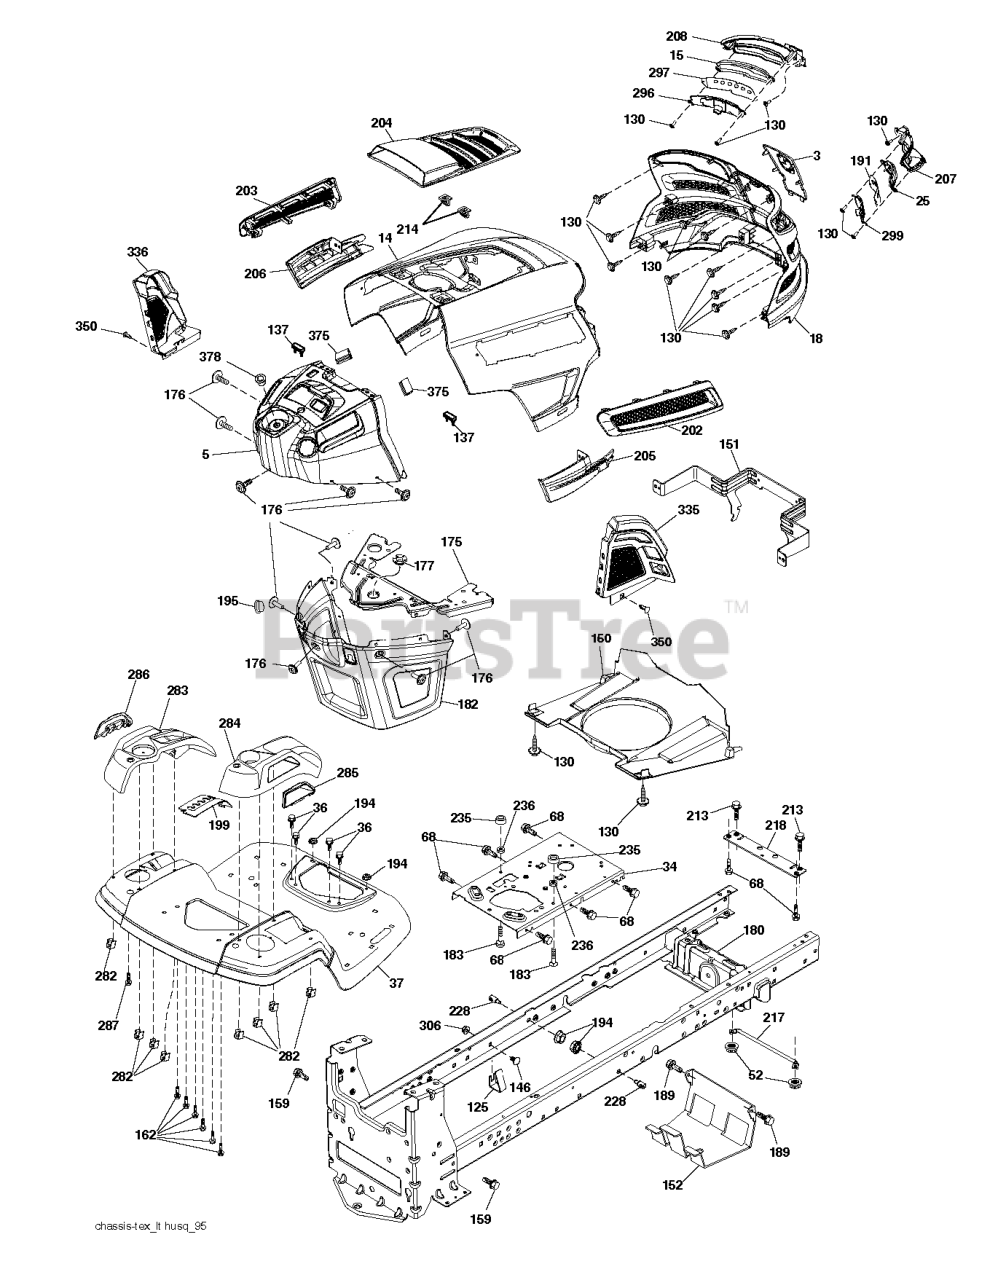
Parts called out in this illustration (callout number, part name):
3	APPLIQUE.SUBASM.GT.HUSQ.II
5	DASHBOARD TEX;GT2;UPPER S_M_
14	HOOD.ASM.HUSQVARNA.GT.TEX.ORAN
15	LED LIGHT.LH
18	GRILLE SUBASM.GT.II.LOW.HDLGHT
25	LENS.RH
34	PLATE.ENGINE.WELDED.CHASSIS
36	SCREW 5/16"
37	FENDER.TLT.FS.W/CUPHLD.ORANGE
52	LOCKNUT
68	SCR 5/16-18 X 1/2 SELFTAP ZN
125	CLIP.FUEL.LINE
130	SCREW.#10 X 0.750.BOS
137	BUMPER DASH
146	BOLT.RDHD.SHT.SQNK.3/8-16X5/8
150	AIR DUCT.GTV2(1.66"RING HEIGHT
151	BRACKET.PIVOT.HOOD.GT.HUSQ.II
152	SHIELD.BROWNING.PNT.GT.V2
159	SCREW, 3/8-16X3/4
162	SCREW.HI-LO.CONSOLE
175	PLATE.PNT.CROSSMEMBER.HUSQ/PRE
176	SCREW.#10-24X5/8.RN.QU
177	BUSHING STEERING
180	CHASSIS
182	DASH.LOWER.COMMON.12V.ADAPTOR
183	BOLT.5/16-18X1-1/4 FULL THD
189	SCREW
191	INSERT INFLECT.RH
194	NUT LOCK HEX FLANGE 5/16-18
195	PLUG.HOLE.DASH.LOWER.12V.BLK
199	PLATE.DECK.LIFT.HUSQ.LT
202	VENT.SIDE.RH.GT.HUSQ.II.
203	VENT.SIDE.LH.GT.HUSQ.II.498
204	VENT.TOP.HUSQ.GT2
205	SIDE.TRIM.RH.GT.HUSQ.II
206	SIDE.TRIM.LH.GT.HUSQ.II.GRAY
207	BEZEL GT2 LED RH W/ LOWER.ATT
208	BEZEL GT2 LED LH W/ LOWER ATT
213	BOLT
214	CLIP.RETAINER.TINNER.
217	ROD.PIVOT.HOOD
218	X-PIECE.HOOD.STOP.NON/
228	STUD.FASTNER.W/ANTI-ROTATE
235	SPACER FENDER
236	NUT.CENTERLOCK.5/16-
282	CLIP.RETAINER.CONSOLE.LT.HUSQ
283	CONSOLE.DECK.LIFT.R.SDFL.HUSQ
284	CONCOLE.CNTRL.PDL.HUSQ.LT.498
285	CONSOLE INSERT RH
286	CONSOLE.INSRT.LH.HUSQ.LT.BLACK
287	SCREW 1/4X20
296	LED LIGHT.LH
297	INSERT REFECT LH
299	LED LIGHT.RH
306	NUT LOCK FLG 3/8-16 UNC
335	COVER.LOWER.DASH.RH.BLACK
336	COVER-LH.LOWER.DASH.GT2.BLACK
350	CLIP.X-MAS.TREE
375	BUMPER CLIP-ON. DASH 1"
378	125B/BVX SERVICE KIT
